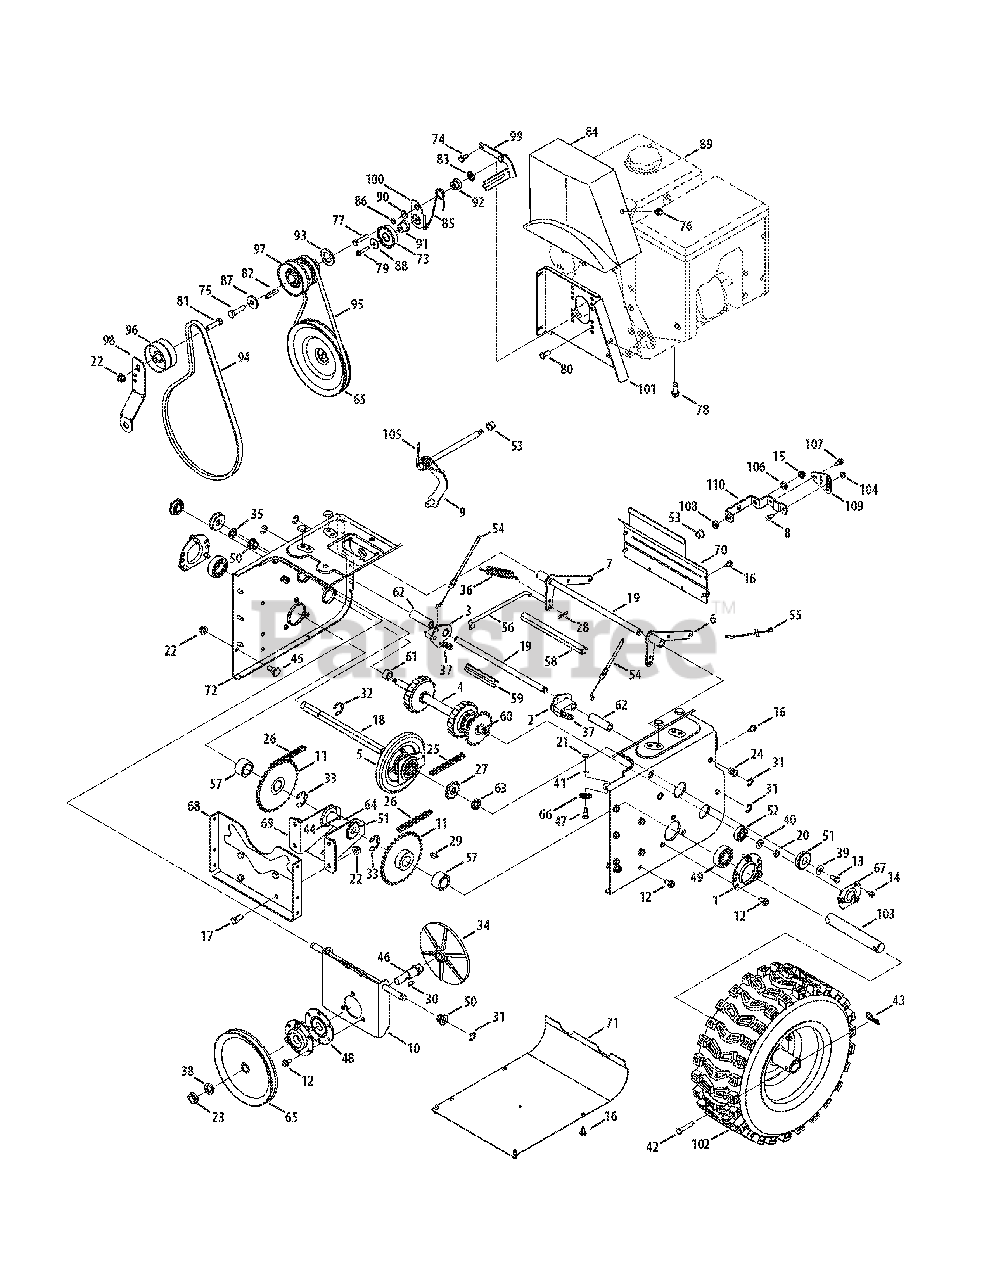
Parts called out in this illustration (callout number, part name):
1	Housing, Bearing
2	Dogg, Steering Drive, LH
3	Dogg, Steering Drive, RH
4	Shaft Assembly, Steering
5	Assembly, Friction Wheel
5	Wheel, Friction, Bonded
5	Screw, Hex Wash
6	Bracket, Auger Actuator
7	Bracket, Drive Actuator
8	Hex Head Screw, 1/4-20
9	Rod Assembly, Shift
10	Bracket, Friction Drive Support
11	Sprocket, 32T
12	TT Screw, 5/16-18 x .750
13	Screw, Hex Cap Lock,
14	Screw, Hex, 1/4-20 x .50
15	Flange Lock Nut, 5/16-18
16	Screw, Hex Wash.
17	Screw, Hex Cap, 3/8-16
18	Shaft, Hex Drive
19	Shaft, Actuator
20	Nut, Hex Insert Jam Lock
21	Nut, Hex, 1/4-28 GR5
22	Nut, Hx Flnge Insert Lk
23	Nut, Hx Insert Jam Lk
24	Rivet Nut, 3/8-16
25	Chain, Endless, #41 x 36L
26	Chain, #420 x 40L
27	Sprocket, #41 x 10T
28	Pin, Internal Cotter
29	Key, Woodruff
30	Key, Hi-Pro, 3/16 x 5/8
31	E-Ring
32	Ring, Retaining
33	Ring, Retainer
34	Plate, Drive
35	Speed Nut, .500
36	Spring, Extension
37	Spring, Extension
38	Washer, Lock, 5/8
39	Washer, Bell., .34 x .872 x .06
40	Wash, .375 x .812 x .060
41	Washer, Lock, 1/4
42	Pin, Clevis
43	Pin, Internal Cotter
44	Fitting, Lube, 3/16 Drive
45	Screw, Shldr., .498 x .34
46	Spindle, Drive Plate
47	Screw, Hex Shldr., 1/4-28
48	Ass’y, Bearing/Housing
49	Bearing, Self Aligning
50	Bearing, Hex Flange
51	Bearing, Ball
52	Bush, Flg, .5625 ID x 1.375 x .4375
53	Bush, Flg, .5 ID x .627 OD
54	Cable, Steering
55	Cable, Auger Idler
56	Rod, Drive Clutch
57	Spacer, 1.01 x 1.50 x .93
58	Spacer, .49 x 7.865
59	Spacer, .49 x 3.545
60	Spacer, .566 x .87 x .190
61	Spacer, .566 x .87 x 1.25
62	Spcr., .514 x .632 x 2.44
63	Spacer, .675 x 1.0 x .23
64	Spcr, .6725 x 1.125 x 2.48
65	Pulley, Drive
66	Roller, Cable
67	Retainer Bracket
68	Bracket, Frame Support
69	Bracket, Axle Support
70	Cover, Upper Frame
71	Cover, Lower Frame
72	Trans Frame
73	Idler Pulley Assembly
74	Screw, Hex Cap, 5/16-24
75	Screw, Hex 3/8-24 x 1.25
76	Screw, Hx Wash Hd Tapp
77	Screw, Hex Cap, 5/16-24 x 1.50
78	Screw, 3/8-16 x 1.00
79	Screw, 1/4-20 x 1.25
80	Screw, Hex Cap, 5/16-24 x .875
81	Screw, Hex Cap, 3/8-16 x 1.75
82	Key, Square, 1/4 x 1.5
83	Nut, Push
84	Cover, Belt
85	Torsion Spring, .850 dia. x .333 lg.
86	Washer, Lock, 5/16
87	Washer, Flat, .406 x 1.25
88	Washer, Flat, .265 x 1.0 x .030
89	Engine Complete
90	Shoulder Spacer, .3175 x .500 x .094
91	Shoulder Spacer, .260 x .785 x .538
92	Shoulder Spacer, .340 x 1.00
93	Spacer, 1.02 x 1.63 x .1425
94	V-Belt, 4L x 44.60
95	V Belt, 3/8 x 36.68
96	Pulley, Flat Idler, 2.75 OD
97	Double Pulley, 3.25 x 2.75
98	Bracket, Auger Idler
99	Belt Keeper Bracket
100	Idler Drive Wheel Bracket
101	Belt Cover Bracket
102	Wheel Ass’y. - LH
102	Wheel Ass’y. - RH
103	Axle, Wheel, 45"
104	Flange Lock Nut, 1/4-20
105	Torsion Spring, .750 I.D. x .968 Lg.
106	Flat Washer, .469 x .875 x .105
107	Shoulder Screw, .368 x .113, 1/4-20
108	Spcr., .5151 ID x .750 OD x .220
109	Speed Selector Pivot Bracket
110	Speed Selector Shift Bracket
